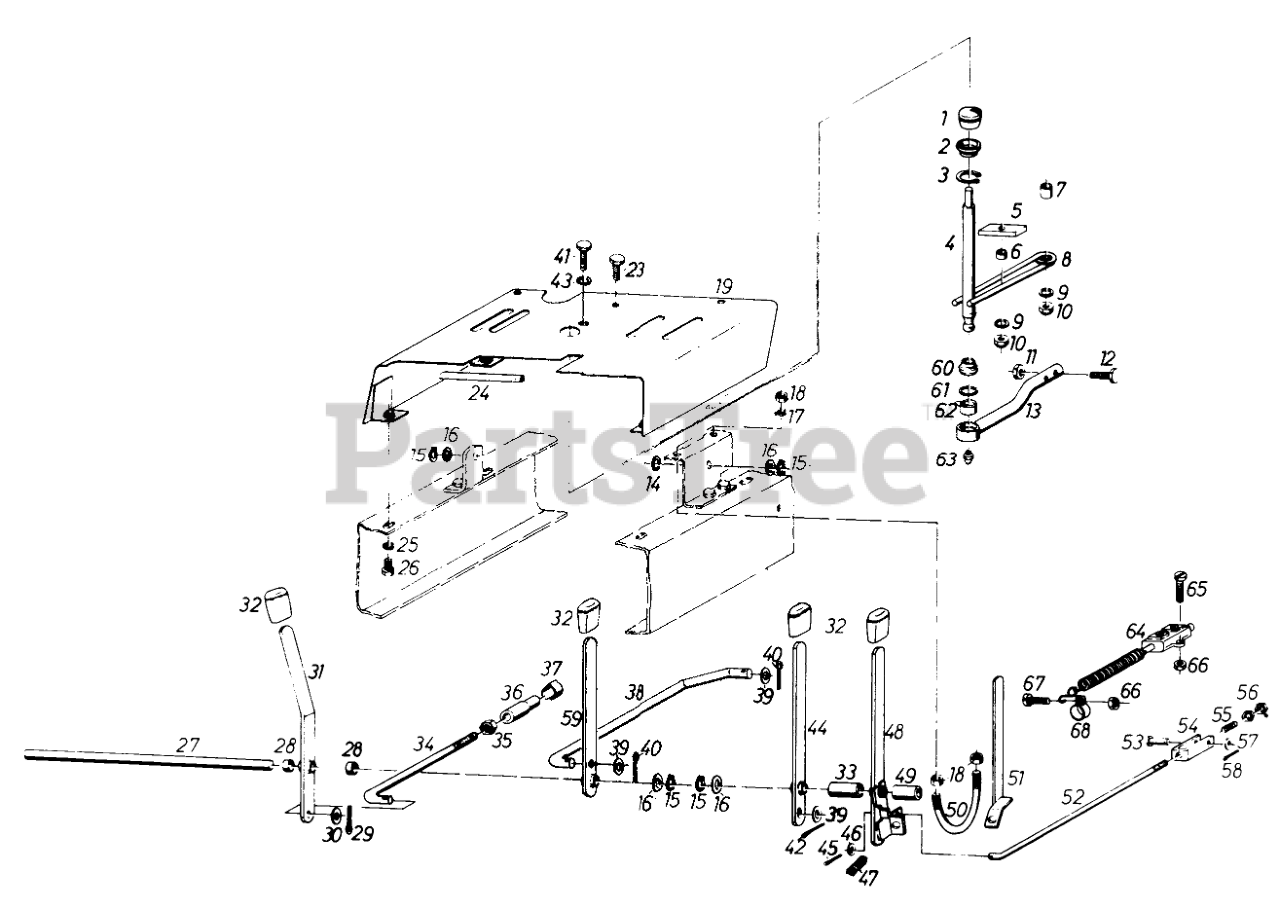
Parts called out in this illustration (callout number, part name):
1	Shift Knob
2	Spacer
3	Circlip
4	Shift Lever
6	Spacer
7	Spacer
8	Spring
9	Washer
12	Screw
13	Shifting Shaft Assy.
15	Circlip
16	Washer
17	Lockwasher
19	Top Frame
24	Profile Cleat
25	Lockwasher
27	Shifting Shaft
28	Spacer
29	Split Pin
30	Washer
31	Shifting Lever
32	Button
33	Spacer
34	Shift Rod
36	Ball Socket
37	Spring
38	Shift Rod
39	Washer
40	Split Pin
41	Screw
42	Split Pin
43	Washer
44	Shifting Lever
45	Split Pin
46	Washer
47	Spring
48	Brake Lever Ens.
49	Spacer
50	Brake Segment
51	Clamping Lever Assy
52	Brake Rod
55	Spring
57	Washer
58	Split Pin
59	Shifting Lever
60	BELLOWS
61	Washer
62	Bearing
63	Grease Fitting
64	STOP LIGHT SWITCH
65	Screw
67	Screw
68	Clamp
